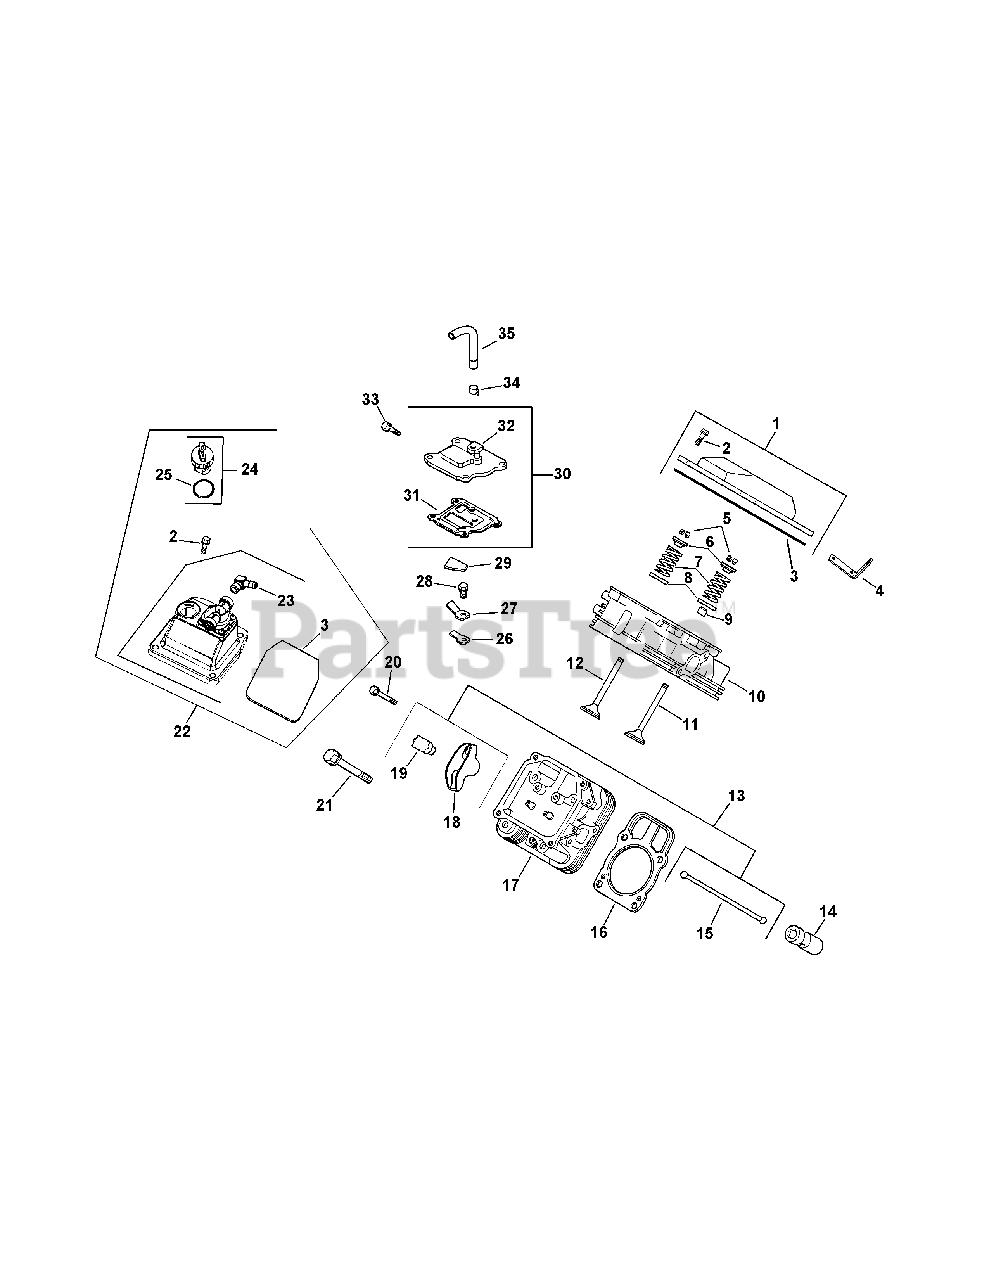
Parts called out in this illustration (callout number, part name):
1	KIT, VALVE COVER-PLAIN
2	SCREW, FLG M6X1.0X30
3	O-RING, VALVE COVER
4	STRAP, LIFTING
5	KIT, RETAINER
6	CAP, VALVE SPRING
7	SPRING, VALVE
8	RETAINER, SPRING
9	SEAL, VALVE STEM
10	KIT, #1 CYLINDER HEAD ASSEMBLY
11	VALVE, INTAKE (STD)
11	VALVE, INTAKE (.25)
12	VALVE, EXHAUST (STD)
12	VALVE, EXHAUST (.25)
13	KIT, VALVE TRAIN
14	LIFTER, VALVE HYDRAULIC
16	KIT, GSKT CYL HD (C22-23 674CC)
17	KIT, #2 CYLINDER HEAD ASSEMBLY
19	PIVOT, ROCKER ARM
20	SCREW, FLG M6X1.0X34
21	SCREW,FLG M10X1.5X90
22	KIT, VALVE COVER-FUEL PUMP
23	KIT, 90 DEG. FITTING
24	CAP ASSY, OIL FILL (YELLOW)
26	REED, BREATHER
27	RETAINER, REED
28	SCREW, FLG THD FRM M5X.8X10
29	FILTER, BREATHER
30	KIT, BREATHER ASSEMBLY
31	GASKET, BREATHER
32	KIT, BREATHER ASSEMBLY
33	SCREW, FLG THD FRM M6X1.0X20
34	CLAMP, HOSE 1/2''
35	BREATHER HOSE
